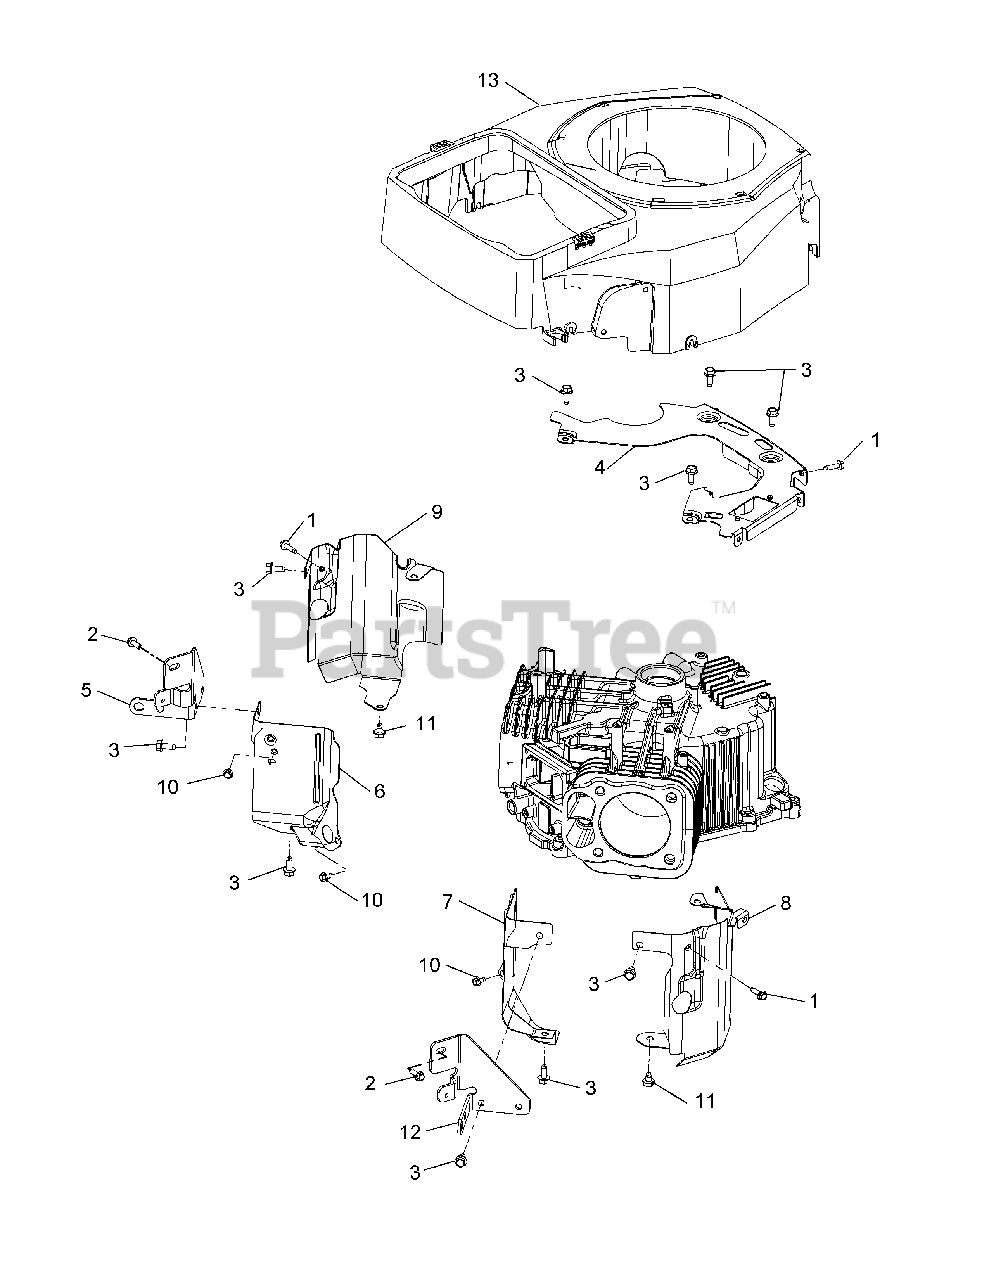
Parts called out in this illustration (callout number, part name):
1	Thread Forming Screw
3	Thread Forming Screw
4	Backing Plate
5	Air Cleaner Base Bracket (#1)
6	Valley Baffle, #1 Cylinder
7	Valley Baffle, #2 Cylinder
8	Left Barrel Baffle
9	Right Barrel Baffle
10	Thread Forming Screw
11	Thread Forming Screw
12	Air Cleaner Base Bracket (#2)
13	Blower Housing Kit
